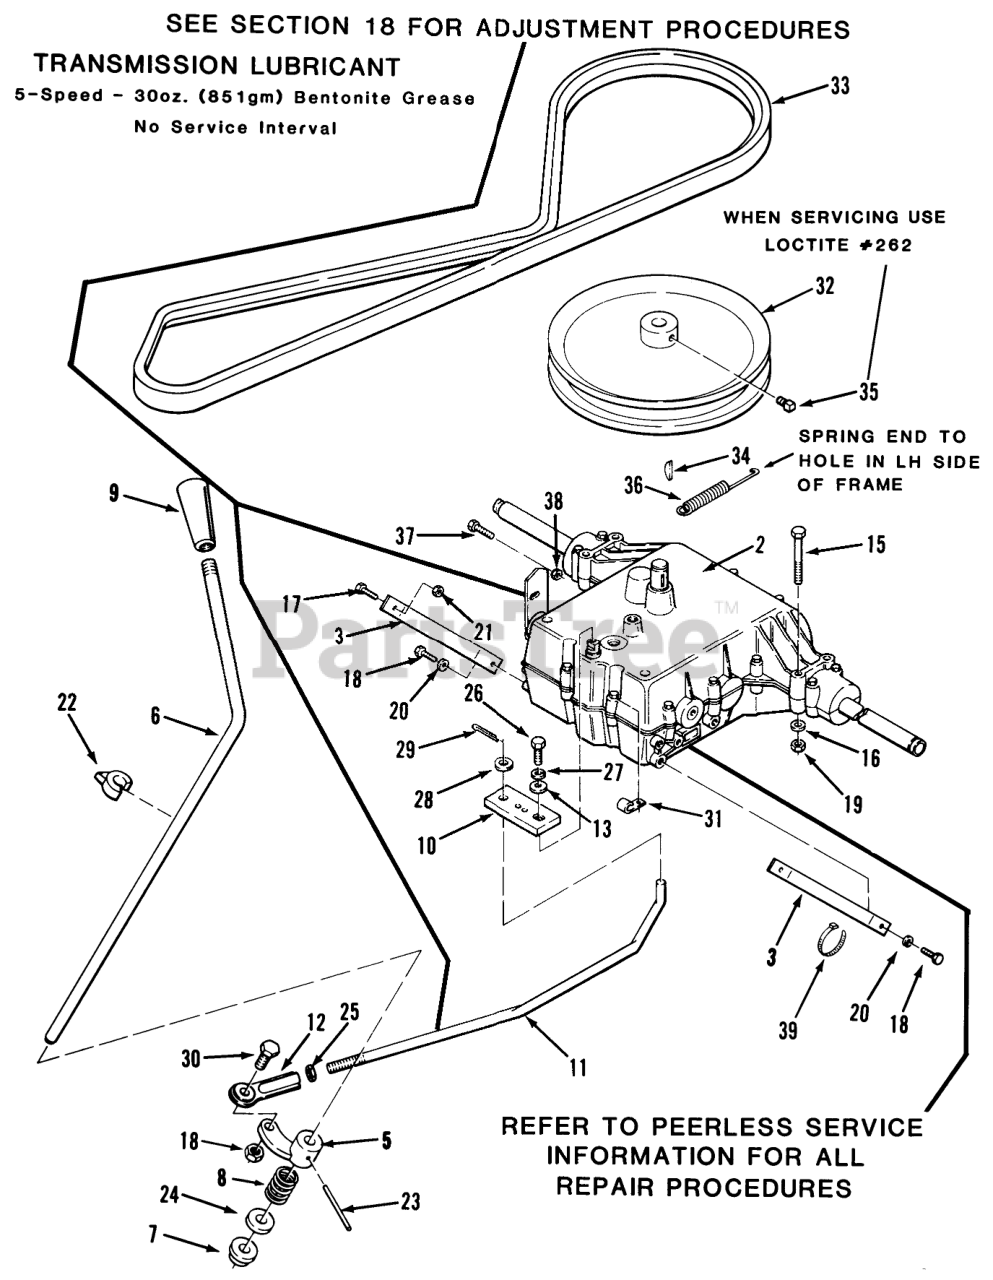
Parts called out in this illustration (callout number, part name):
1	Trans.-5-Spd.(Peerless Model 920-009)
1	ASS'Y TRANSAXLE 5-SP
3	TORQUE-STRAP R
5	ARM SHIFTER B
6	Shaft
7	Bushing-Nylon
8	SPRING COMPRESSION
10	ARM-TRANSMISSION 5SP
11	ROD-LINKAGE
12	END-ROD
13	WASHER
15	SCREW-HH
16	WASHER-PLAIN
17	CARRIAGE BOLT -4
18	Screw
19	NUT-LOCK, NI
20	WASHER-LOCK
21	Nut
22	POINTER
23	SPIROL PIN 7/32X21/2
24	SHIM-WASHER
25	NUT-JAM
26	SCREW-HH
27	WASHER-LOCK
28	WASHER 5/16 SAE
29	PIN-COTTER
30	SCREW-HH
31	J-CLIP
32	PULLEY-TRANS
33	BELT-V
34	KEY-HI-PRO
35	SCREW-SQH
36	SPRING-EXTENSION
37	SCREW-HH
38	Nut
39	PLASTIC TIE
